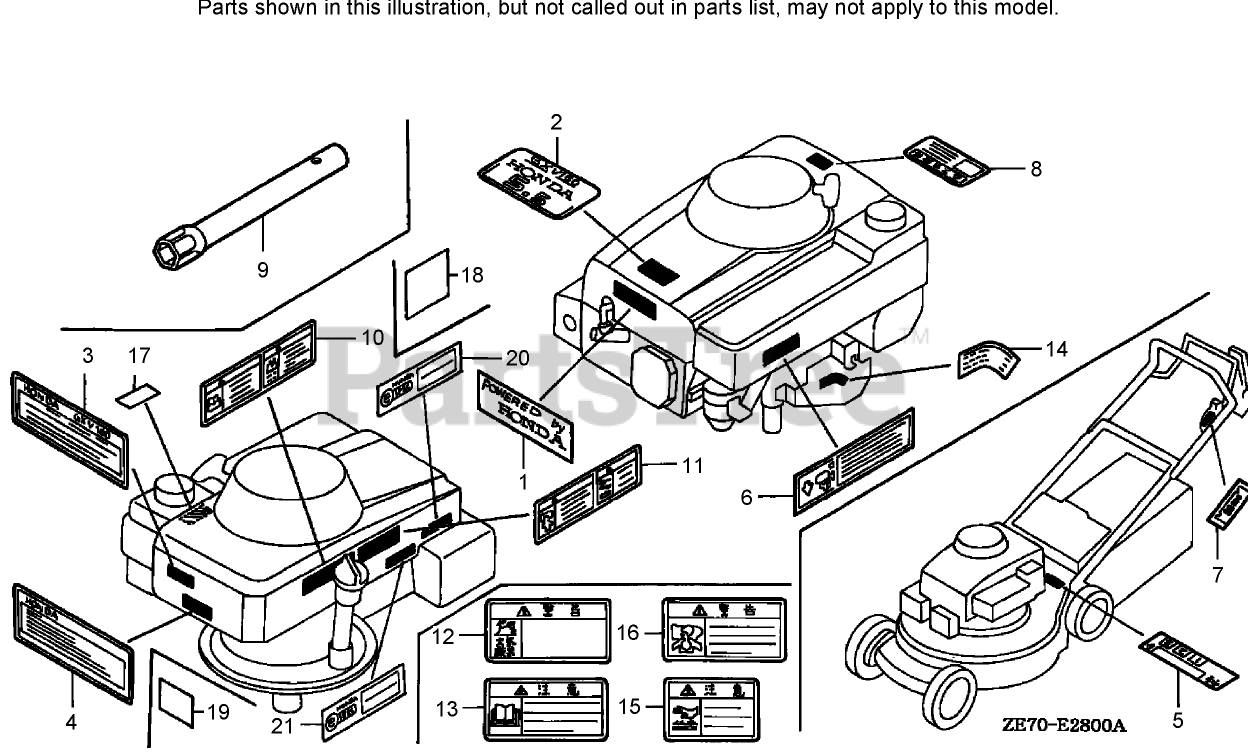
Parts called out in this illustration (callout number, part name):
2	MARK-EMBLEM (5.5 ES)
2	MARK-EMBLEM (5.5) (AH)
9	Wrench-Box (P21)
19	MARK-TYPE (N1AH)
